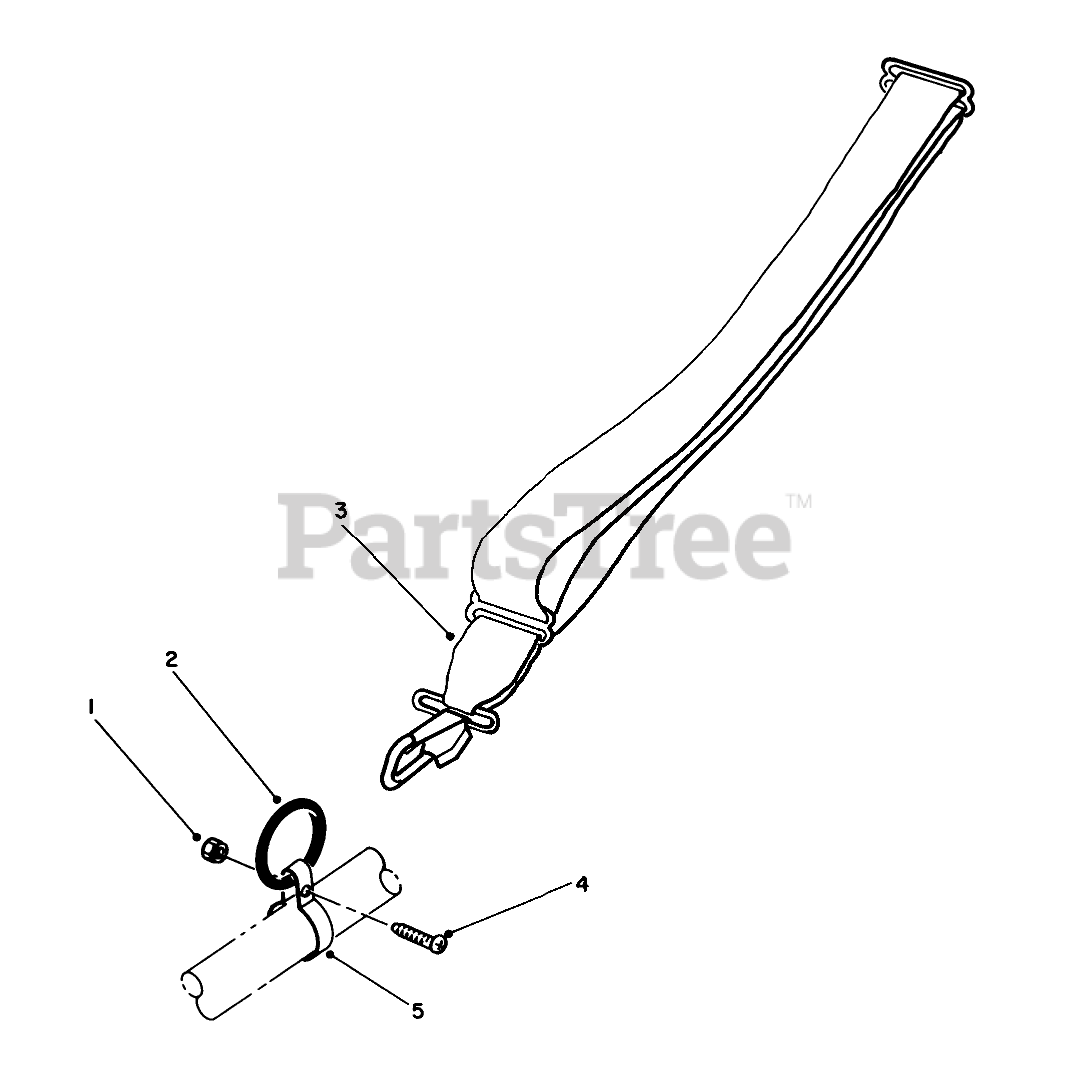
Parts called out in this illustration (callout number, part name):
1	NUT-LOCK, NI
2	Ring
3	Harness
4	SCREW-SRH
5	Clamp
